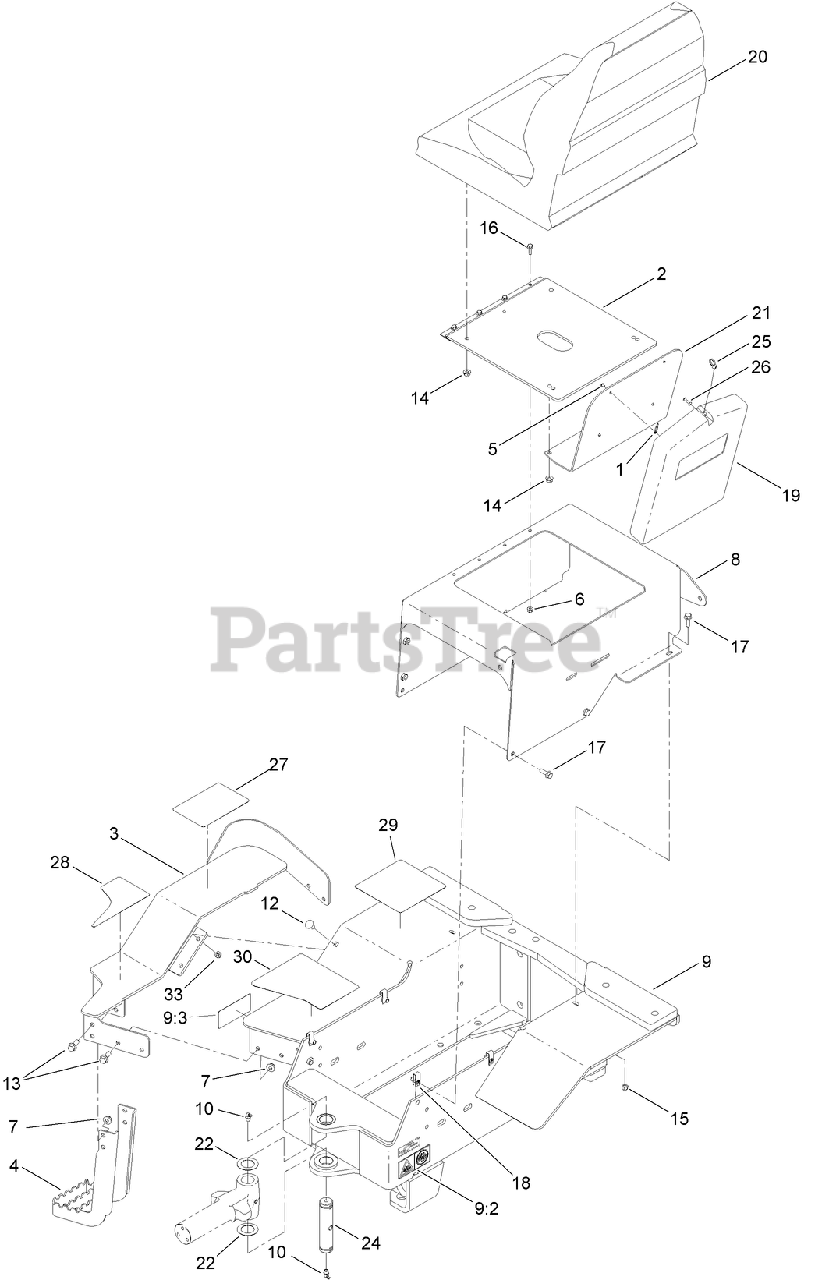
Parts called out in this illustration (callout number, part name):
1	LANYARD
2	PLATE-SEAT
3	PLATFORM-EXTENSION
4	STEP-PLATFORM
5	RIVET-POP
6	NUT-FLANGE, NI
7	NUT-HF, NI
8	SUPPORT-SEAT
9	REAR FRAME AND DECAL ASM
9:2	DECAL-DANGER, ARTICULATED JOINT
9:3	DECAL-WARNING, STEP EXTENSION
10	FITTING-GREASE
12	SCREW-CARR
13	SCREW-HHF
14	NUT-FLANGE
15	NUT-LOCK, NI
16	SCREW-HHF
17	SCREW-HHF
19	HOLDER-MANUAL, OPERATOR
20	SEAT-NON SUSPENSION
21	PLATE-MOUNT, OPERATOR MANUAL
24	PIN-PIVOT
25	STRAP-TIE, NYLON
26	POST-MANUAL
27	TREAD-FLOORBOARD
28	TREAD-FLOORBOARD
29	TREAD-FLOORBOARD
30	TREAD-FLOORBOARD
33	NUT-LOCK, NI
